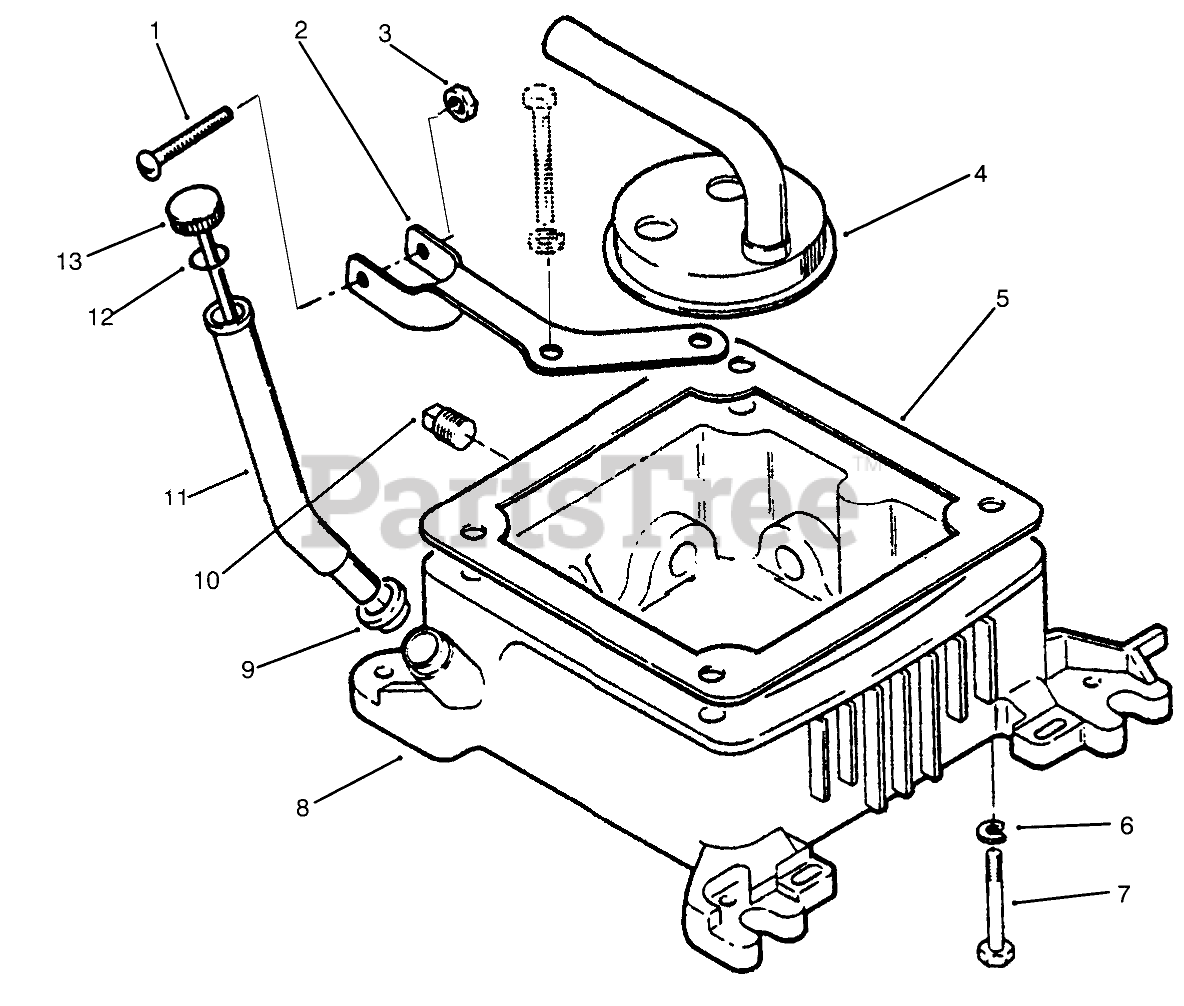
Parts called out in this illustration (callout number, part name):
1	SCREW - PAN HEAD
2	BRACKET-FILL TUBE
3	NUT - SPEED
4	OIL CUP ASM
5	GASKET
6	WASHER-FLAT
7	HHCS 3/8-16 X 3 3/4
8	Base-Oil(Incl. Ref. #10)
9	SEAL-OIL FILL TUBE
10	PLUG - SQUARE HEAD
11	Tube-Oil Fill
12	SEAL 0-RING
13	Cap & Indicator-Oil Fill (Incl . Ref. #12)
